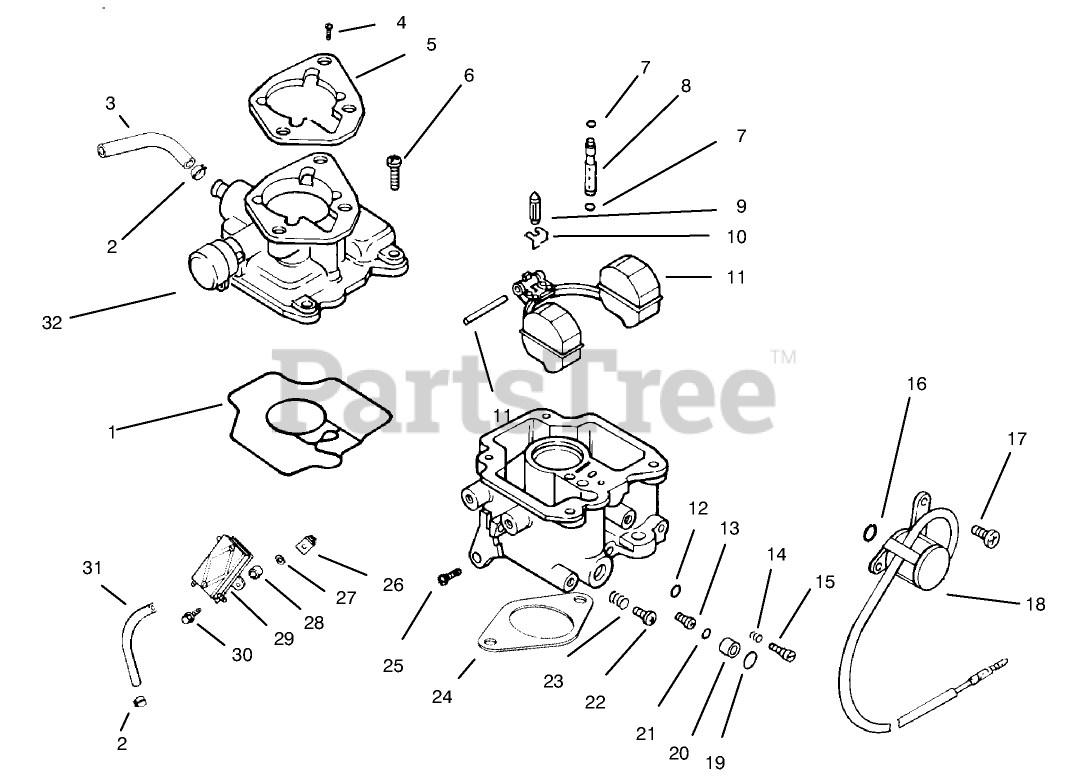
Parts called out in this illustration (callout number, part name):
1	Gasket-Body,Carburetor
2	Clamp
3	Line fuel
4	Screw
5	Gasket
6	Screw
7	"O"Ring
8	Jet-Slow
9	Valve-Inlet Needle
10	Clip, cable
11	Roat Repair Kit
12	"O"Ring
13	Jet-Main
14	Spring-Idle Adj.
15	Needle, idle
16	O-Ring
17	Screw
18	Solenoid
19	O-Ring
20	Seat-Solenoid
21	O-Ring
22	Screw, idle adjusting
23	Spring-Idle Speed Adj.
24	Gasket
25	Screw-Throttle Stop
26	Nut
27	Washer
28	Spacer
29	Pump-Fuel
30	Screw
31	Line, fuel
32	Kit-Choke Repair (Incl. Ref. # 33
